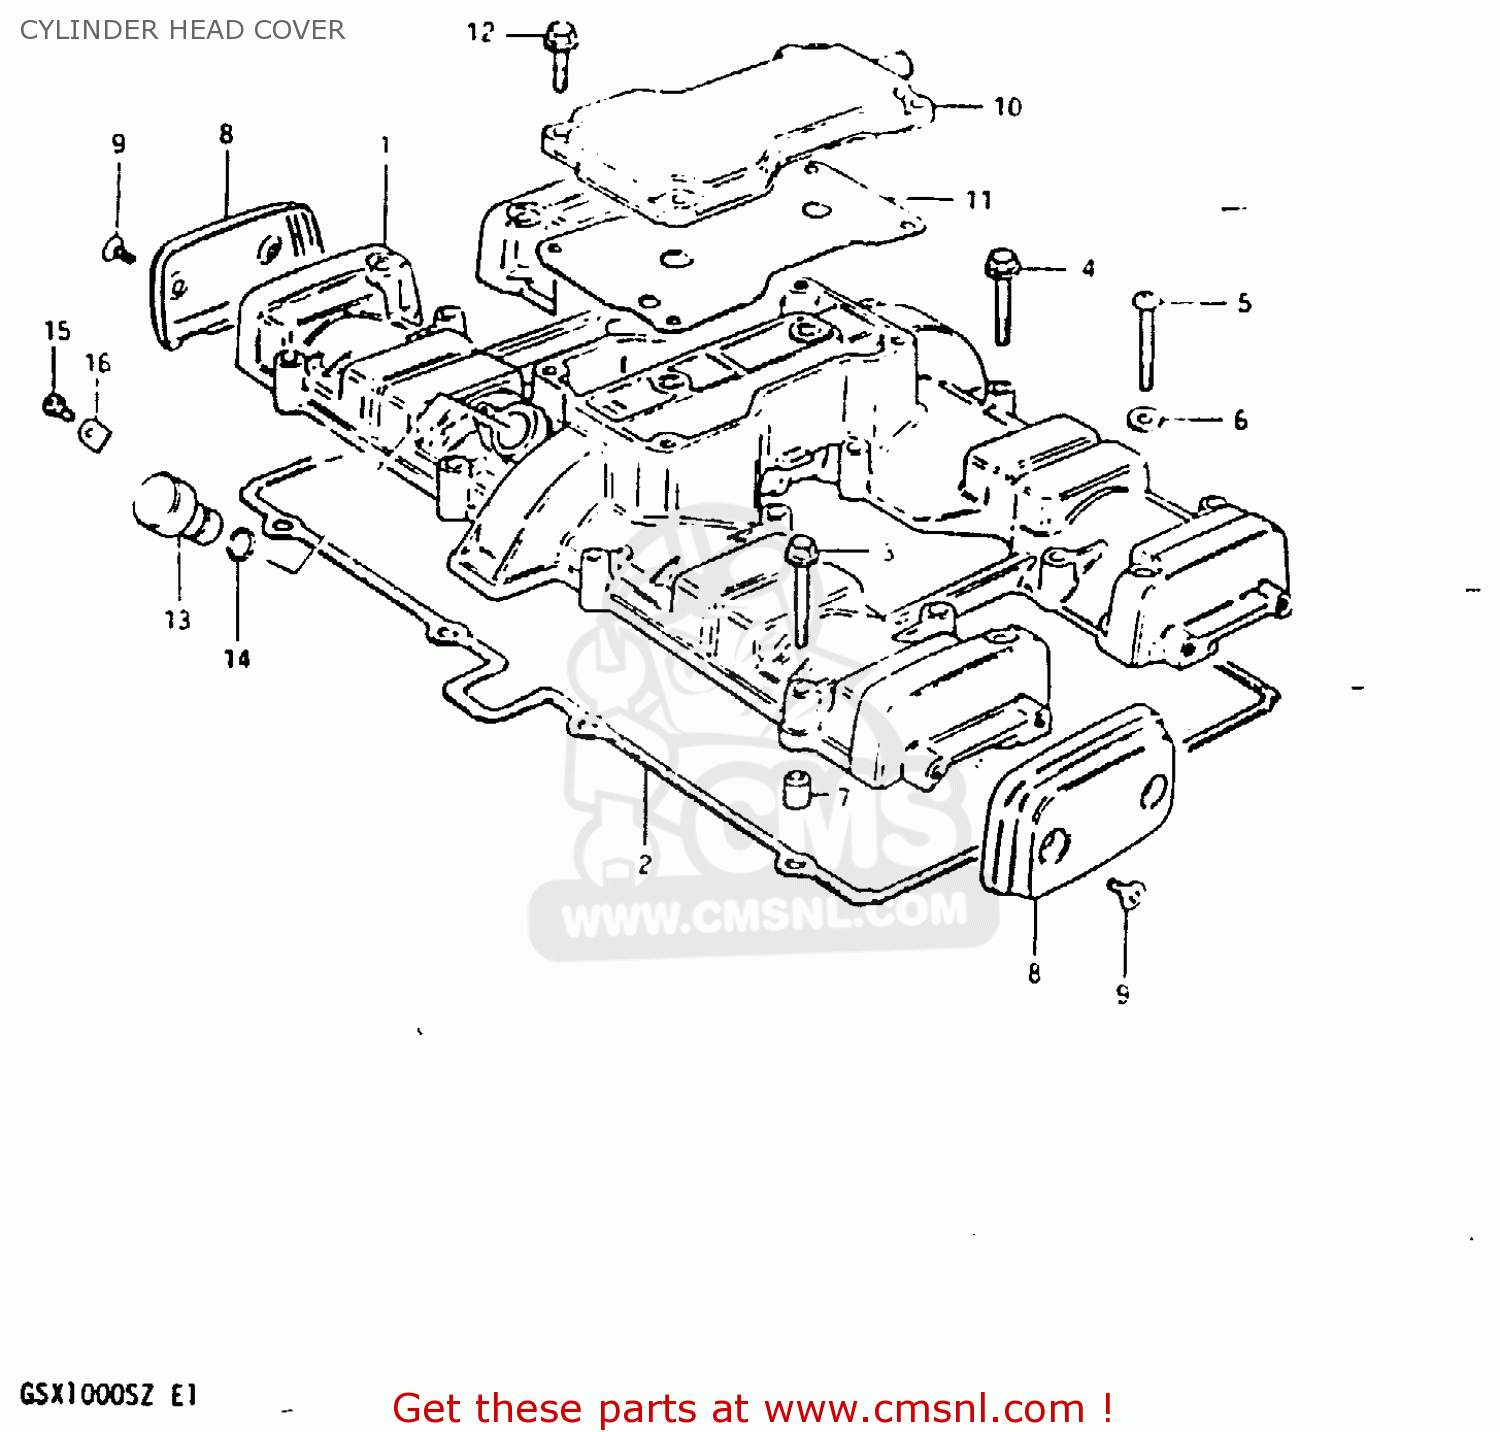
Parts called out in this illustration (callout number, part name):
1	COVER,CYLINDER HEAD
2	GASKET,CYLINDER HEAD COVER (MCA)
3	BOLT
4	BOLT 6X35
5	SCREW 6X40
6	GASKET (NAS)
7	PIN(6.2X8X11)
8	CAP,CYLINDER HEAD COVER
9	SCREW(5X12)
10	COVER,BREATHER
11	GASKET (MCA)
12	BOLT,REAR
13	PLUG,TACH GEAR SLEEVE HOLE
14	SEAL,TACHOMETER DRIVEN
15	SCREW(5X12)
16	PLATE,TACH DRIVE GEAR SLEEVE
